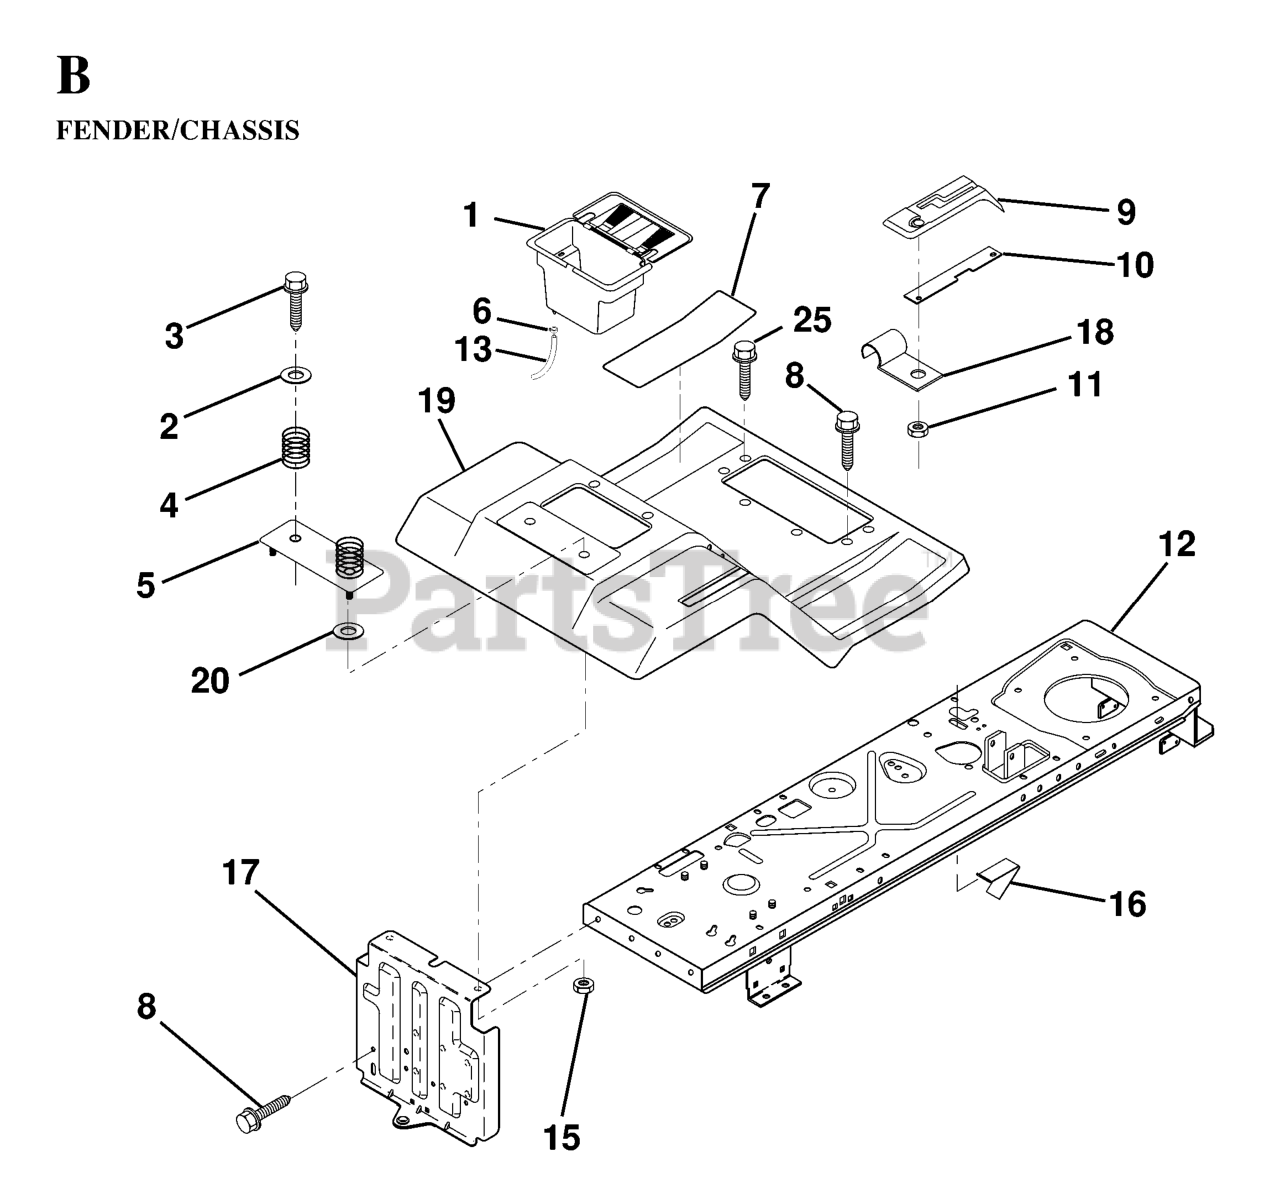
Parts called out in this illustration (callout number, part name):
1	BATTERY CASE
2	WASHER
3	SCREW
4	SPRING COMPRESSION
5	PLATE ASM BATTERY
6	HOSE CLAMP T
7	FOOTREST PAD
8	SCREW.THDROL.5/16-18X3/4.TTY
9	CONSOLE,SHT CONTR
10	BAR, SHIFT LOCK
11	NUT.PUSH.3/16
13	TUBE BATTERY DRAIN
15	Nut, Keps Blk Hex 1/4-20 UNC
16	SWITCH ACTUATOR
18	CLIP,INSULATOR
19	FENDER/FOOTREST
20	WASHER
25	Screw Hex Wsh Thdroll 5/16-18 x 1
